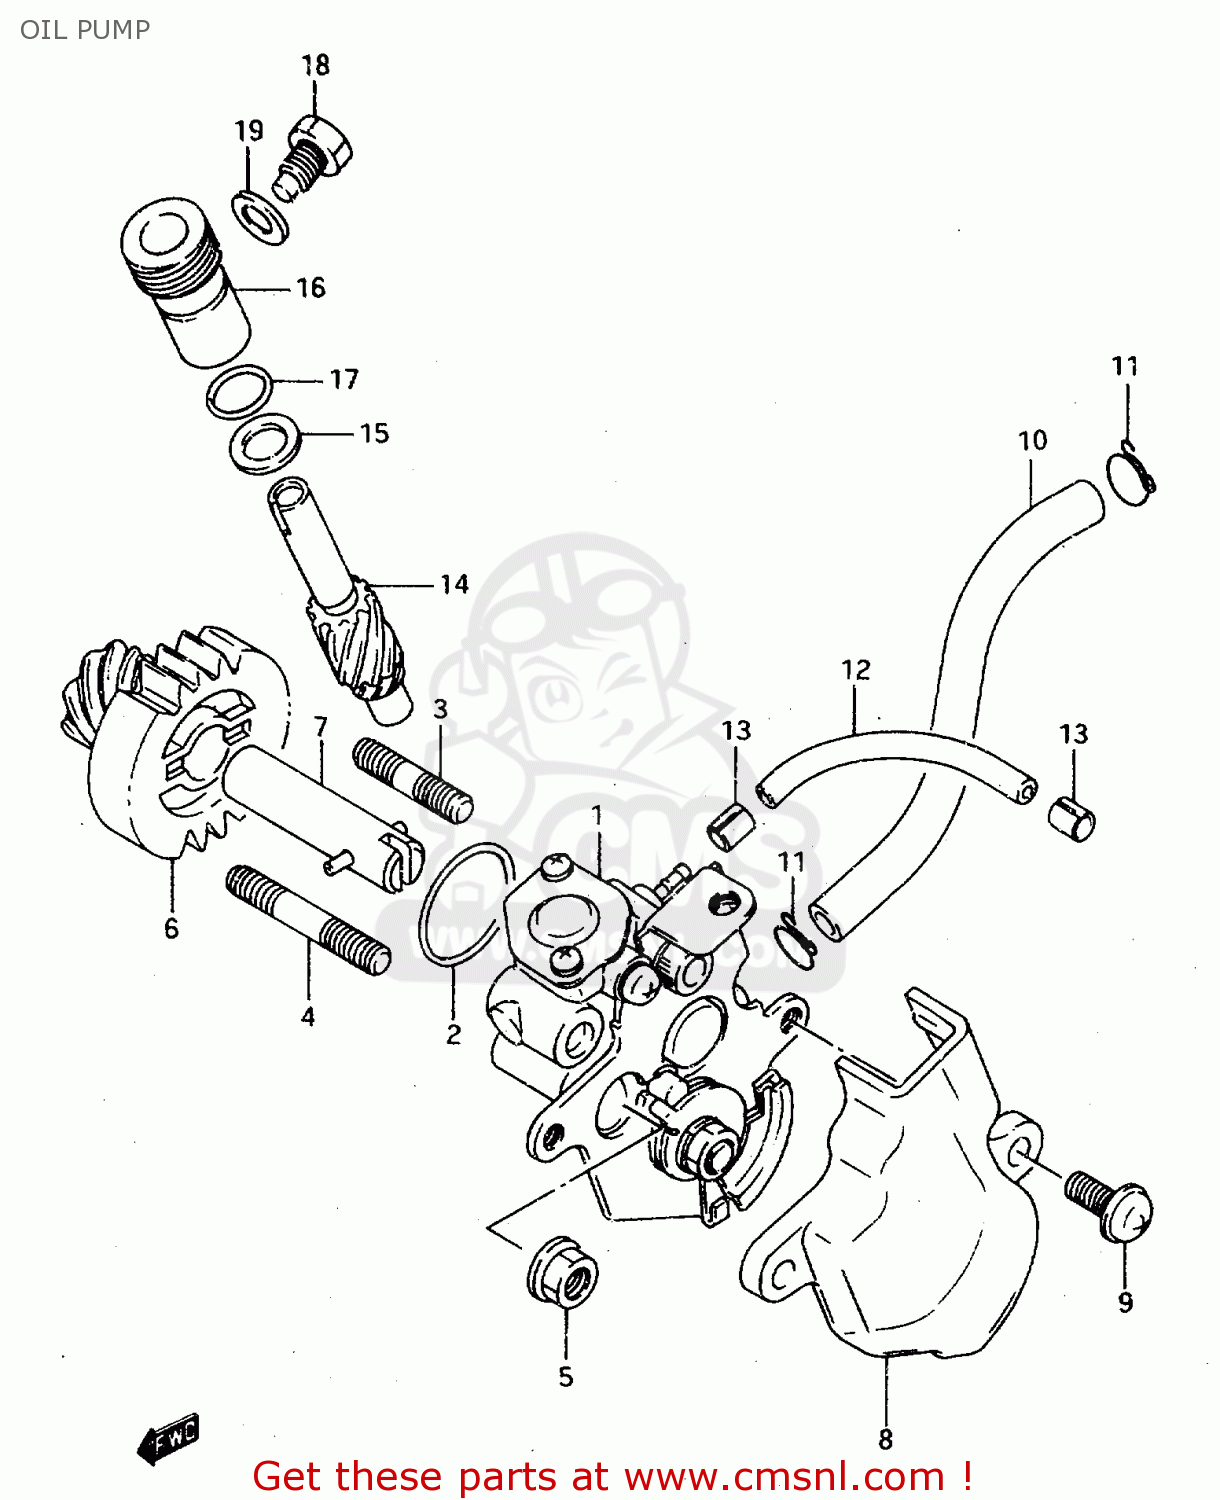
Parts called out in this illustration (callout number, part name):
1	PUMP ASSY,OIL
2	O RING(D:1.5,ID:19.5)
3	BOLT,STUD(5X18)
4	BOLT,STUD(5X28)
5	NUT
6	GEAR,OIL PUMP DRIVE
7	SHAFT,OIL PUMP GEAR
8	COVER,OIL PUMP
9	SCREW
10	HOSE (4.5X8.5X300)
11	CLIP
12	HOSE (2X5X300)
13	CLIP
14	GEAR,TACHOMETER DRIVEN
15	WASHER(8X13.7X1)
16	SLEEVE,TACHOMETER DRIVEN GEAR
17	O RING(D:1.3,ID:9.6)
18	BOLT
19	GASKET(6.2X11X1).2 (NAS)
